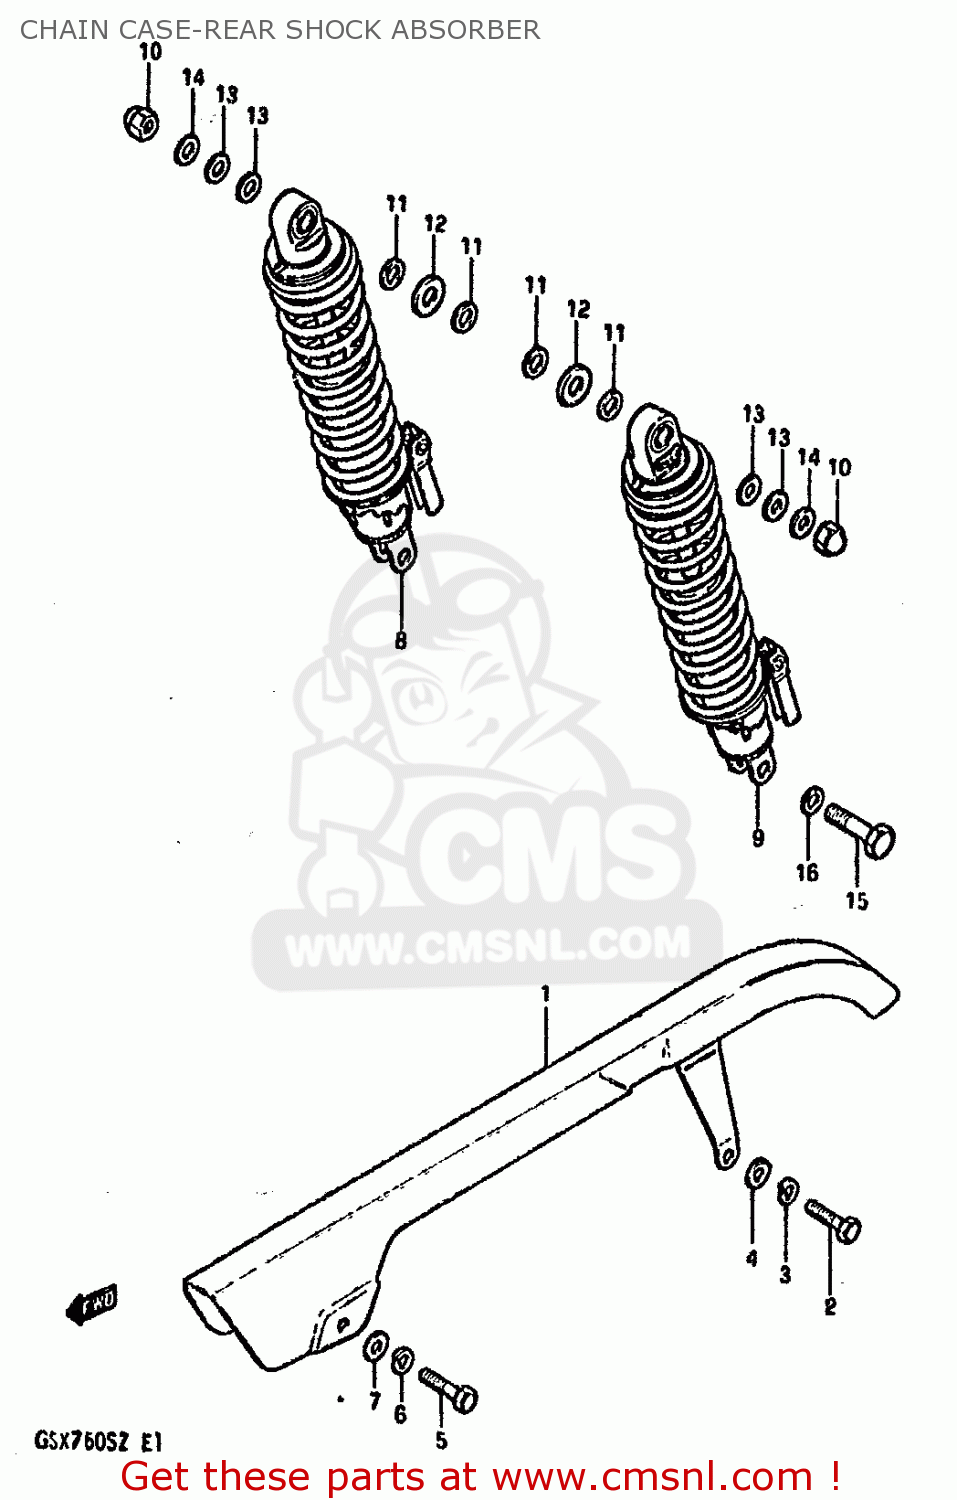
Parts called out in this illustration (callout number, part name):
1	CASE,CHAIN
2	BOLT
3	LOCK WASHER
4	WASHER
5	BOLT
6	LOCK WASHER
7	WASHER
8	SHOCK ABSORBER, REAR RH
9	SHOCK ABSORBER, REAR LH
10	NUT, LOWER LH
11	WASHER
12	WASHER (12.5X24X3.2)
13	WASHER
14	WASHER(10.5X24X3.2)
15	BOLT(10X36)
16	WASHER
